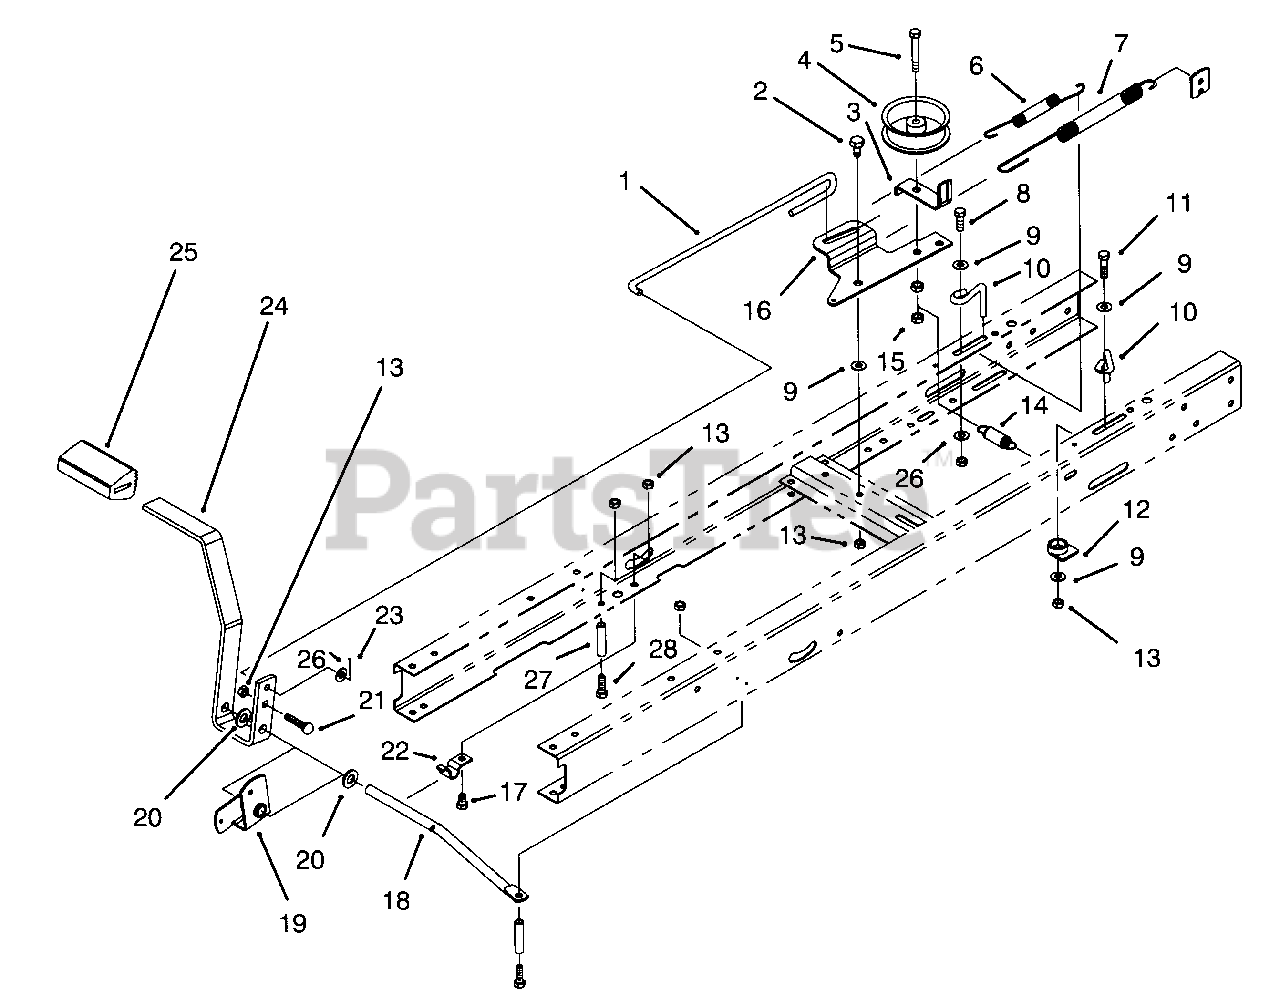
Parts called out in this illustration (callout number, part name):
1	Rod-Clutch/Brake
2	Bolt-Shoulder
3	Guide-Idler Belt
4	Pulley-Flat Idler
5	Screw-Hex Hd. Cap
6	Spring-Pedal Return
7	Spring-Brake
8	Screw-Hex Hd. Cap
9	Washer-Flat
10	Guide-Trans. Belt
11	Screw-Hex Hd. Cap
12	Guide-Cable
13	Nut-Lock
14	Spring-Extension
15	Nut-Lock
16	Arm-Idler
17	Screw-Hex Hd. Cap
18	Rod-Pedal Pivot
19	Bellcrank
20	Washer-Flat
21	Bolt-Carriage
22	Clamp-Shift Pivot
23	Pin-Cotter
24	Pedal-Clutch/Brake
25	Pad-Pedal
26	Washer-Flat
27	Spacer-Tube
28	Screw-Hex Hd. Cab
